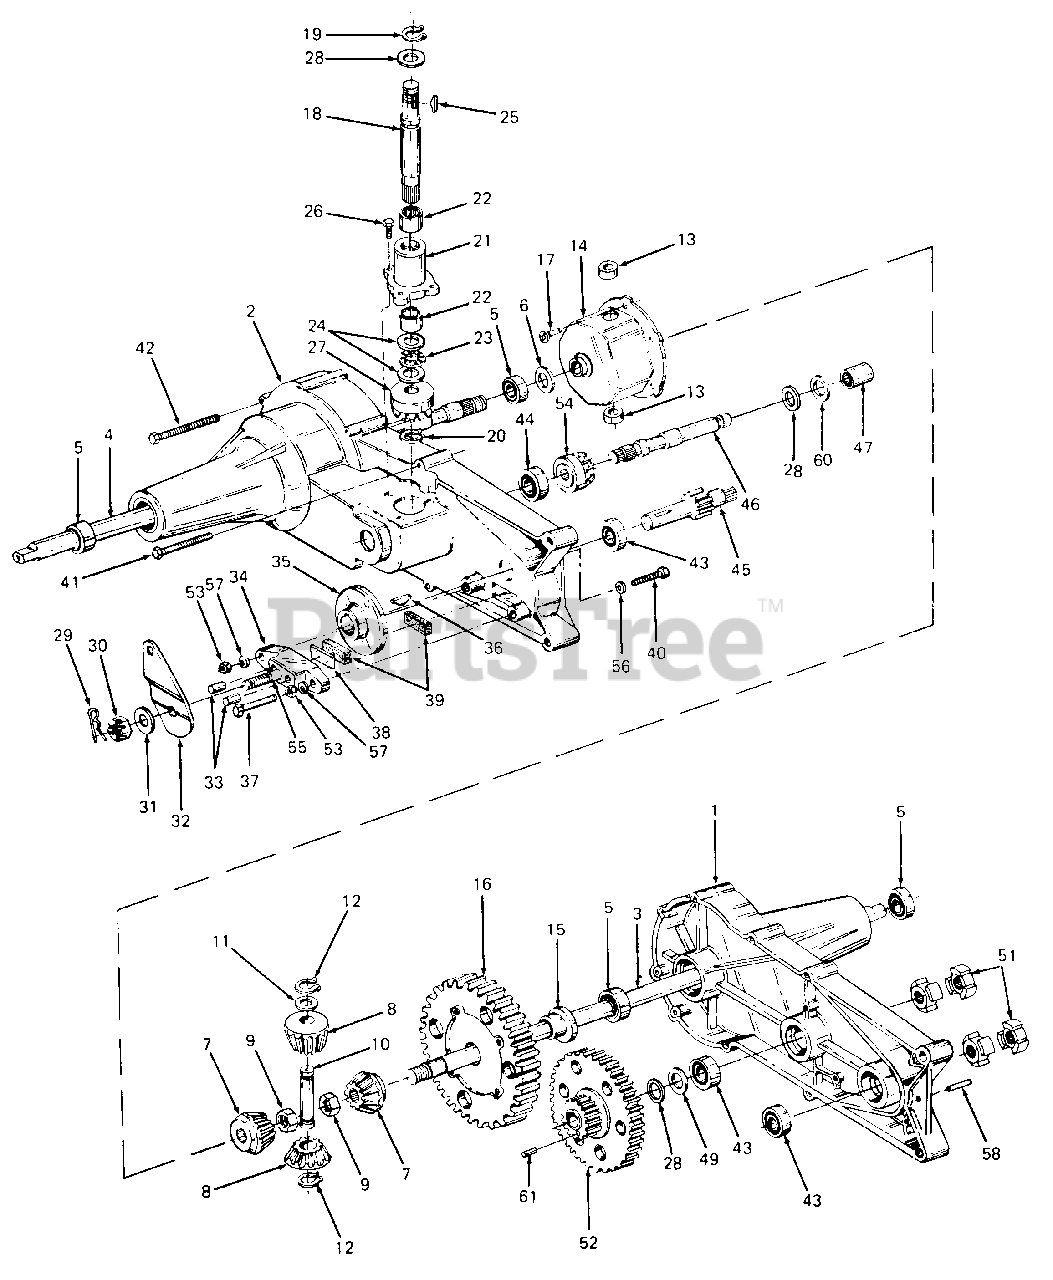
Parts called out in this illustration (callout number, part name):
1	Housing Half: L.H.
2	Housing Half: R.H.
3	Axle: L.H.
4	Axle: R.H.
5	Bearing: Ball
6	Washer: Flat: .76 x 1-1/8" x .306 Thk. Hdn.
7	Gear: Miter
8	Gear: Miter
9	Nut: Hex Jam Patch Lock: 1/2-20
10	Shaft: Cross
11	Washer: Flat: 505 I.D. x 1.0
12	Ring: Snap
13	Bearing: Thrust
14	Housing Ass'y. Differential
15	Bearing: Flange: .75 I.D. x .587
16	Gear: Differential: 72 Tooth
17	Screw: Pan Hd. Patch Lock 1 1/4-20 x .50 Lg.
18	Shaft: Input
19	Ring: Snap
20	Ring: Retaining: Ext. 7/16 Dia.
21	Bearing: Input Housing
22	Bearing: Needle: 5/8 I.D. x .50 Lg.
23	Bearing: Thrust
24	Washer: Flat: 5/8 I.D. x 1.12 O.D. x .030 Thk.
25	Key #4 Hi-Pro: 3/32 x 5/8 Dia.
26	Screw: Hex Patch Lock: 1/4-20 x 3/4 Lg.
27	Gear: Input Pinion: 17 Tooth
28	Washer: Flat: .62 I.D. x 1.0 O.D. x .030 Thk.
29	Pin: Cotter
30	Nut: Castle: 5/16-24
31	Washer: Flat: .343 x .88 x .062 Thk.
32	Arm: Brake Actuator
33	Pin: Actuating: 5/16 Dia.
34	Yoke: Brake
35	Disc: Brake
36	Key: Hi-Pro: 3/16 x 5/8 Dia.
37	Screw: Hex Patch Lock: 1/4-20 X 1.5 Lg.
38	Plate: Puck
39	Puck: Brake
40	Screw: Hex Cap: 1/4-20 x 1.5 Lg.
41	Screw: Hex Self-Tap: 1/4-20 x 2.0 Lg.
42	Screw: Hex Self-Tap: 1/4-20 x 2.75 Lg.
43	Bearing: Ball
44	Bearing: Ball
45	Shaft: Pinion w/11 Tooth Gear
46	Shaft: Drive
47	Bearing: Needle
49	Washer: Flat: 5/8 x 1.12 x .060 Thk.
51	Coupling
52	Gear: Tooth 60 & 17
53	Nut: Hex Jam: 1/4-20
54	Gear: Drive Pinion: 17 Tooth
55	Bolt: Square Hd. 5/16-24
56	Washer: Flat: .265 x .938 x .12 Thk.
57	Washer: Lock: 1/4
58	Pin: Roll: 3/16 Dia. x .50 Lg.
60	Bronze Thrust Brg. 518" I.D.
61	Dowel Pin 3/32" x 1/4"
